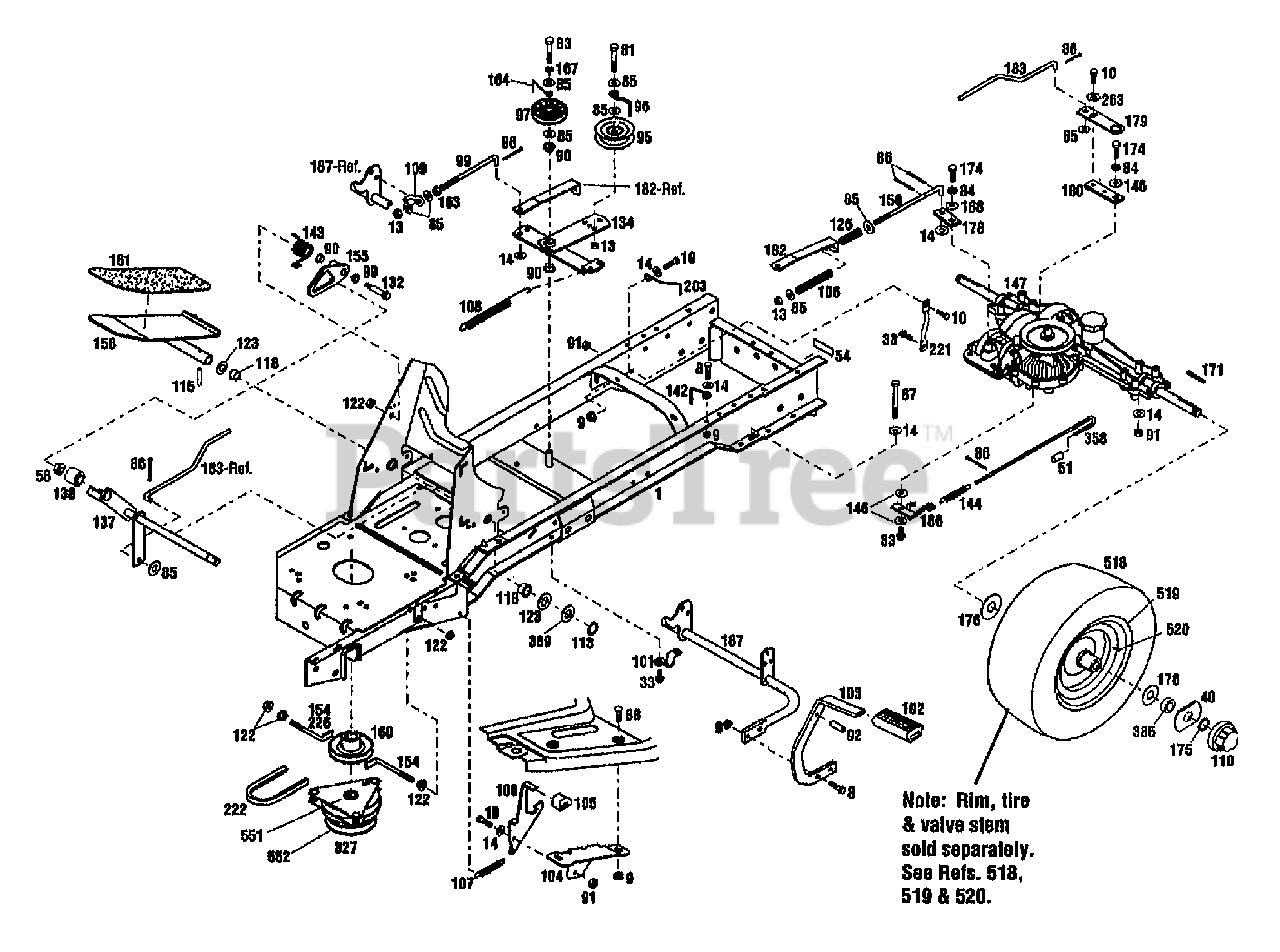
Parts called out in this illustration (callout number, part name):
1	ASSM-FRAME LTX
8	SCR-HH 5/16-18X1.0 G5 ZP
9	NUT-HFLK 5/16-18 ZP
10	SCR-HHC 5/16-18X.75 GR 5 ZP
13	NUT-LOCK 3/8-16
14	WASHER-FLAT 5/16 SAE
33	SCR-HFLK 5/16-18X.75
40	WASHER-SPEC .75X2.50
51	GRIP-HANDLE
54	DECAL-TRANS RELEASE
58	NUT-HT LK 1/4-20
81	SCR-HH 3/8-16X2.0 G5 ZP
83	SCR-HH 3/8-16X1.75 G5 ZP
84	WASHER-LK .25 ZP
85	WASHER-FLAT 3/8 SAE
86	PIN-COTTER .09X.75 ZP
87	SCR-HH 5/16-18X2.75 G5 ZP
88	SCR-CARR 5/16-18X.62 G2 ZP
90	BUSHING-.5X.5 NYLON FLNG
91	NUT-TOP/LK 5/16-18 ZP
92	PIN-DRIVE .312X.75
96	GUIDE-BELT
97	PULLEY-IDLER
99	ROD-CLUTCH
100	LATCH-BRAKE CLUTCH USE1771514
101	CLIP-CLAMP .75 ID
102	PAD-FOOT PEDAL
103	PEDAL-BRAKE
104	BRKT-BRAKE LOCK
105	PAD-BRAKE
106	SPRING-COMPRESSION
107	SPRING-EXTENSION
108	SPRING-EXTENSION
109	ROD-PIVOT
110	CAP-HUB
113	RING-RETAIN .625 ID
115	PIN-ROLL .188X1.0
118	BEARING-FLANGE
122	NUT-HFLK 3/8-16 ZP
123	WASHER-1.115X.637X.06
126	SPRING
132	SCR-SHLDR 3/8-16
134	ARM-IDLER
137	SHAFT-HYDRO PIVOT
138	BEARING-BALL
142	GUIDE-BELT
143	SPRING-TORSION
144	SPRING
146	WASHER-FLAT 5/16 SAE
147	TRANSAXLE-HYDRO
150	ROD-BRAKE
154	RETAINER-CLUTCH
155	ARM-RETURN NEUTRAL HYDRO
158	ASSM-PEDAL HYDRO
160	PULLEY-ENGINE
161	PAD-FOOT PEDAL
163	NUT-HEX 3/8-16 ZP
164	GUIDE-BELT
167	WASHER-LK .375 @ DEPL
171	KEY-3/16X3/16X1 3/4
174	SCR-HHC 1.4-28 X .50
175	RING-RET."E".577 ID
176	WASHER-1.87X.765X.06 SPECIAL
178	BRAKE-ARM
179	ARM-CONTROL
180	ARM-HYDRO
182	BRACKET-BRAKE
183	ROD-HYDRO CTRL
186	BRACKET-DUMP VALVE
187	ASSM-BRAKE PEDAL
188	WASHER-FLAT .25 DIA
203	GUIDE-BELT
221	SUPT-TRANSAXLE
222	BELT-V
226	GUIDE-BELT
263	WASHER-LK .312 PYRAMIDAL
327	CLUTCH-ELECTRIC
358	ROD-DUMP VALVE
385	SPACER-1.0X.766X.413
389	WASHER-1.0X.64X.029
518	TIRE-20X8.00-10
519	WHEEL-REAR
520	STEM-VALVE
551	BEARING-UPPER CLUTCH
552	BEARING-CLUTCH LOWER
